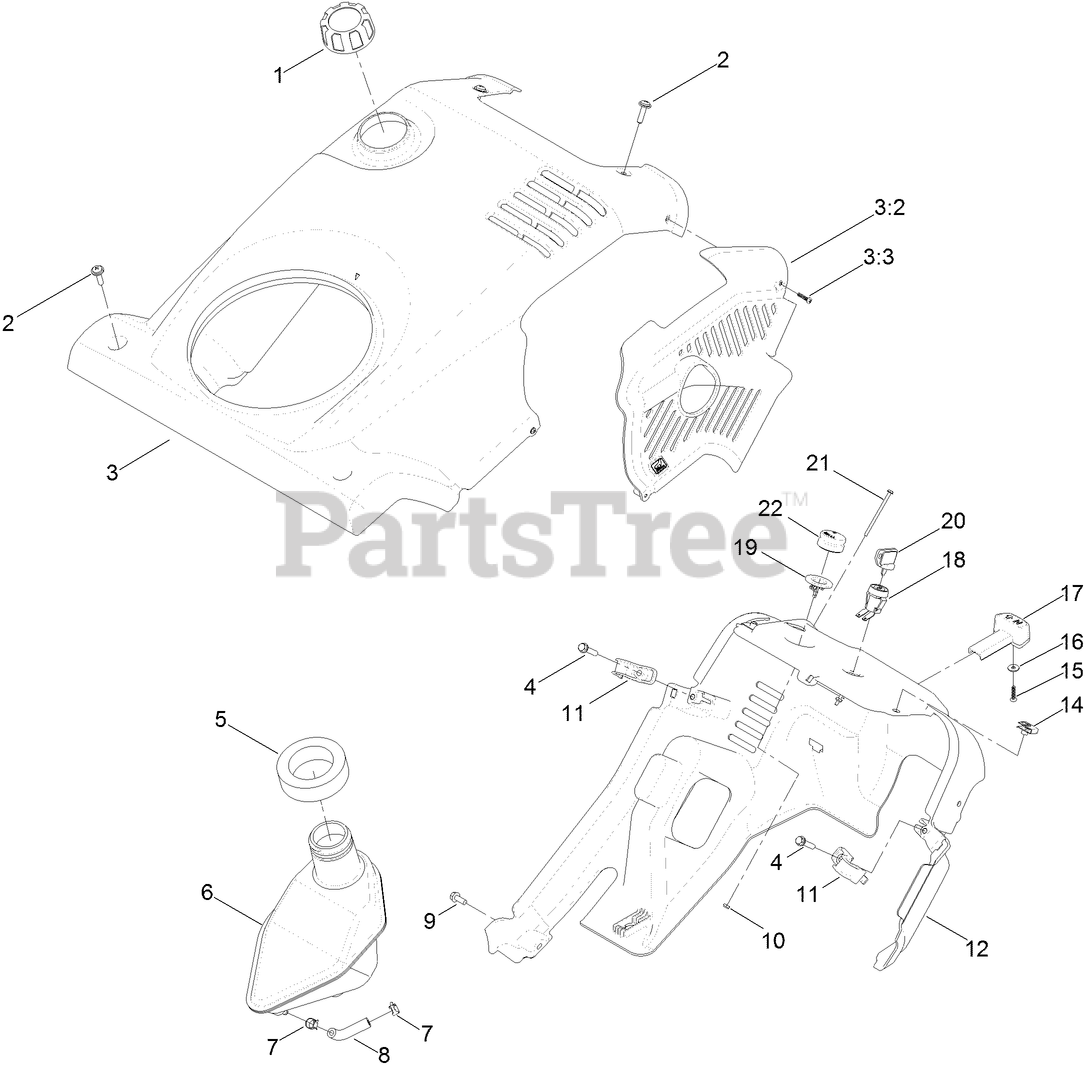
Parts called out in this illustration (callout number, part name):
1	FUEL CAP ASM
2	SCREW-PPH
3	SHROUD ASM
3:2	BAFFLE-EXHAUST
3:3	SCREW-PPH
4	SCREW-PLASTITE
5	SEAL-TANK
6	TANK-FUEL, GAS
7	CLAMP-HOSE
8	HOSE-FUEL
9	SCREW-HWH
10	NUT-HEX
11	CLIP-SHROUD
12	SHROUD-LOWER
15	SCREW-PPH
16	WASHER-PLAIN
17	KNOB-CHOKE
18	SWITCH
19	BODY-PRIMER
20	KEY-IGNITION
21	SCREW-HWH
22	BULB-PRIMER
